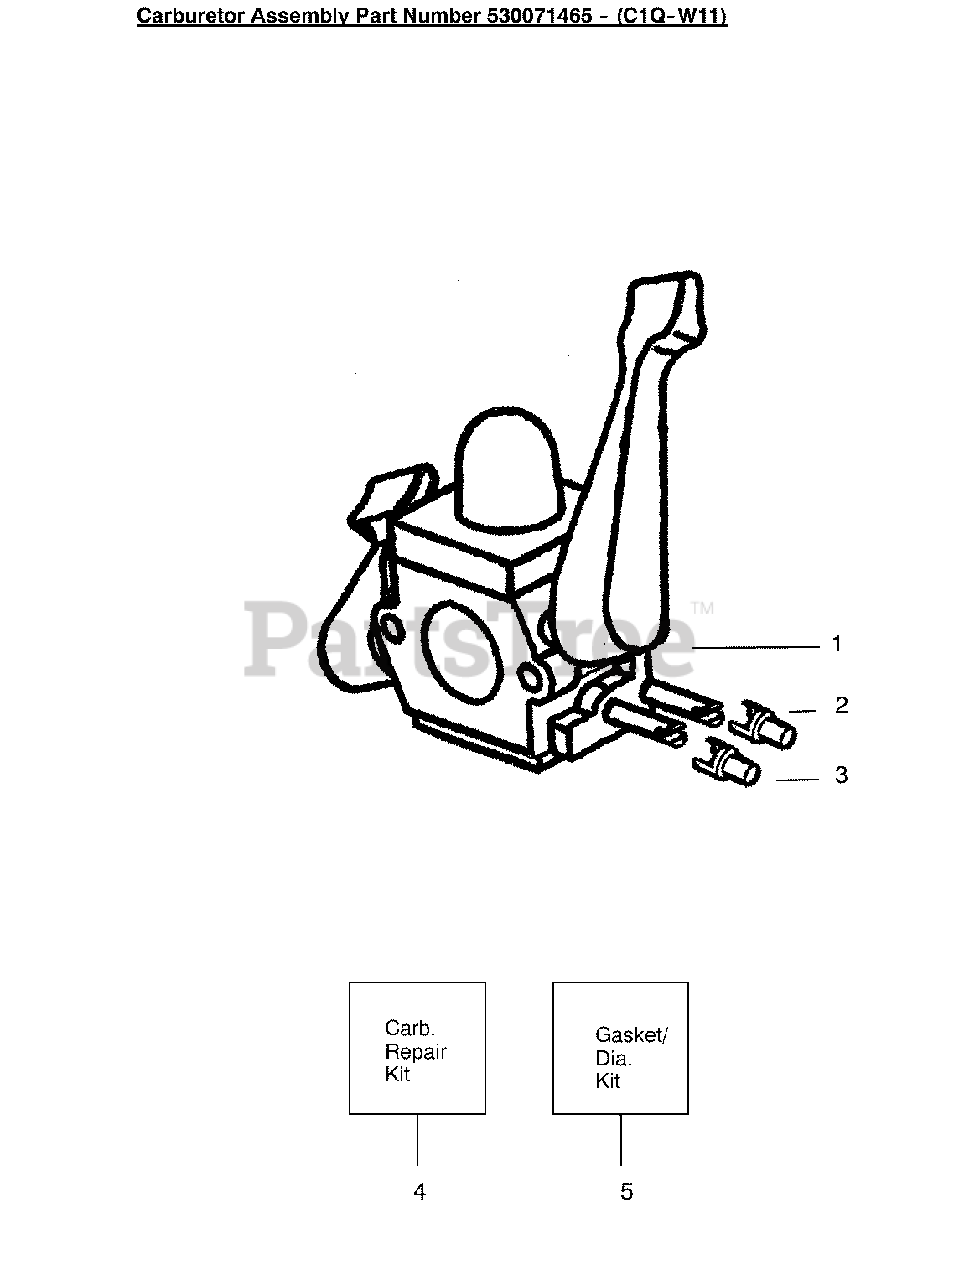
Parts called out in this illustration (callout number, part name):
1	Assy-Carb. Zama (C1Q-W11)
2	Cap-Limiter (high) brown
3	Cap-Limiter (low) tan
4	Kit-Carb. Repair
5	Kit-Carb. Gasket (Zama)
530071465	Carburetor Assembly (C1Q-W11)
